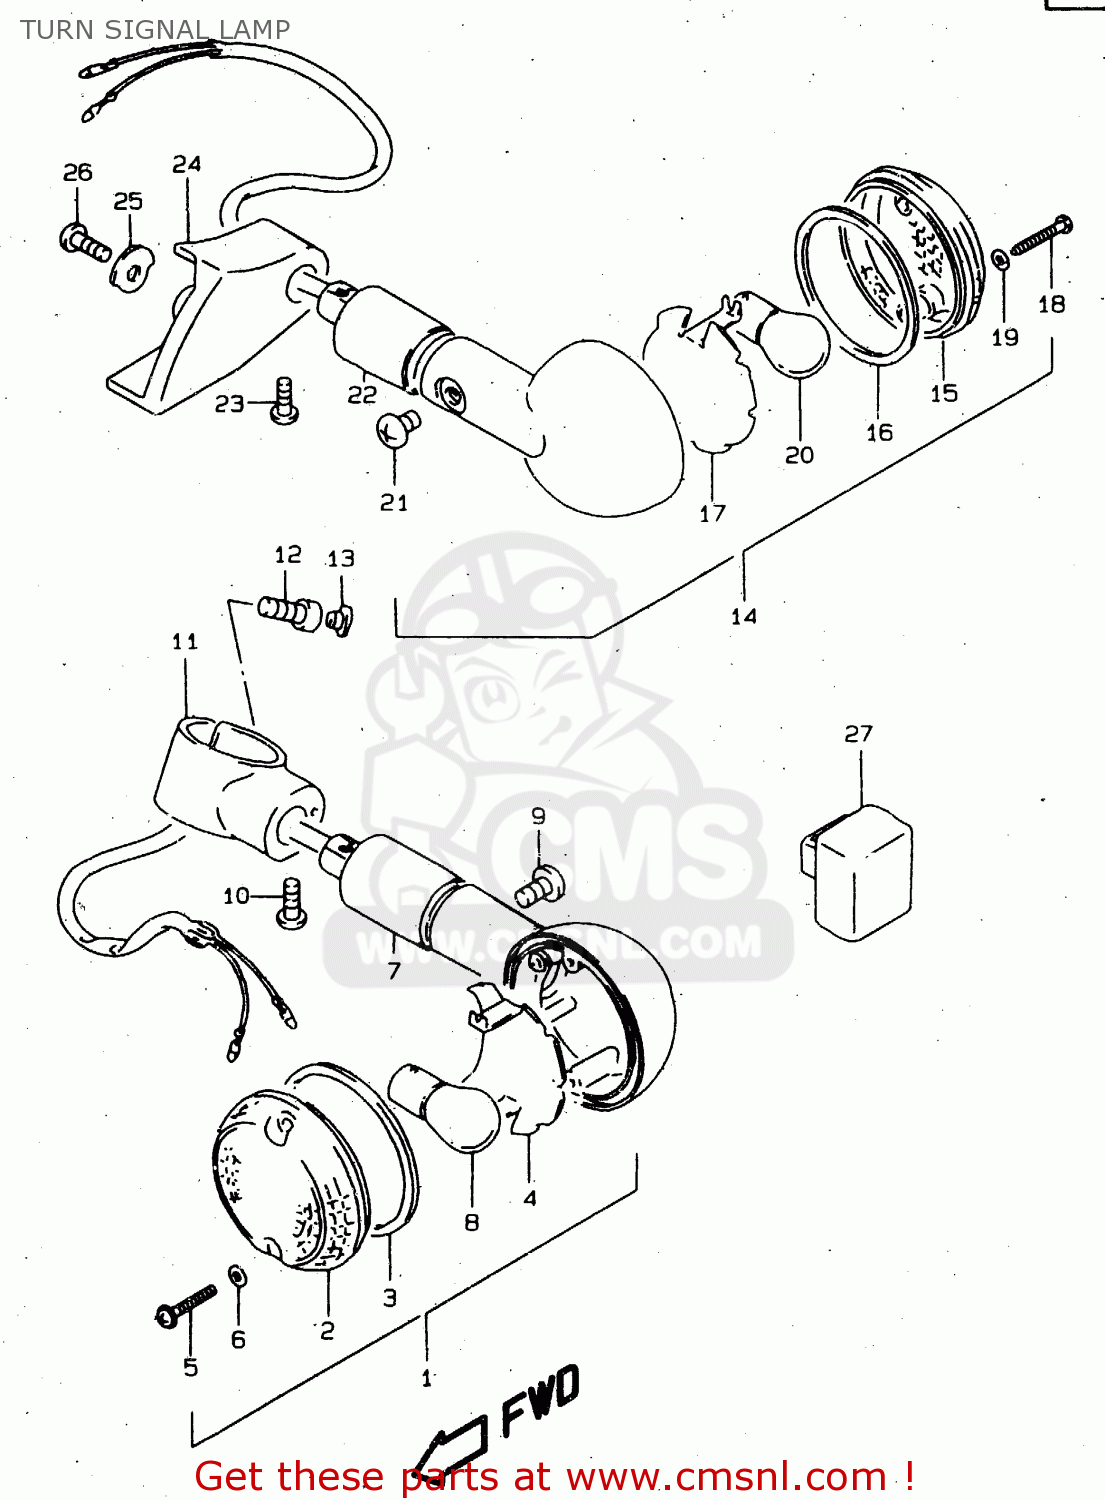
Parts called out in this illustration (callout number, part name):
1	LAMP ASSY,FR TURN SIGNAL
2	LENS
3	GASKET (NAS)
4	REFLECTOR
5	SCREW
6	GASKET (NAS)
7	STAY,TURNSIGNAL LAMP
8	BULB(12V21W)
9	SCREW
10	SCREW
11	BRACKET,FR TURNSIGNAL LAMP,R
12	BOLT
13	CAP(OD:10)
14	LAMP ASSY,RR TURNSIGNAL,R
15	LENS
16	GASKET (NAS)
17	REFLECTOR
18	SCREW
19	GASKET (NAS)
20	BULB(12V21W)
21	SCREW
22	STAY,TURNSIGNAL LAMP
23	SCREW
24	BRACKET,RR TURNSIGNAL,R
25	WASHER,RR TURNSIGNAL BRACKET
26	SCREW 6X12
27	RELAY ASSY
